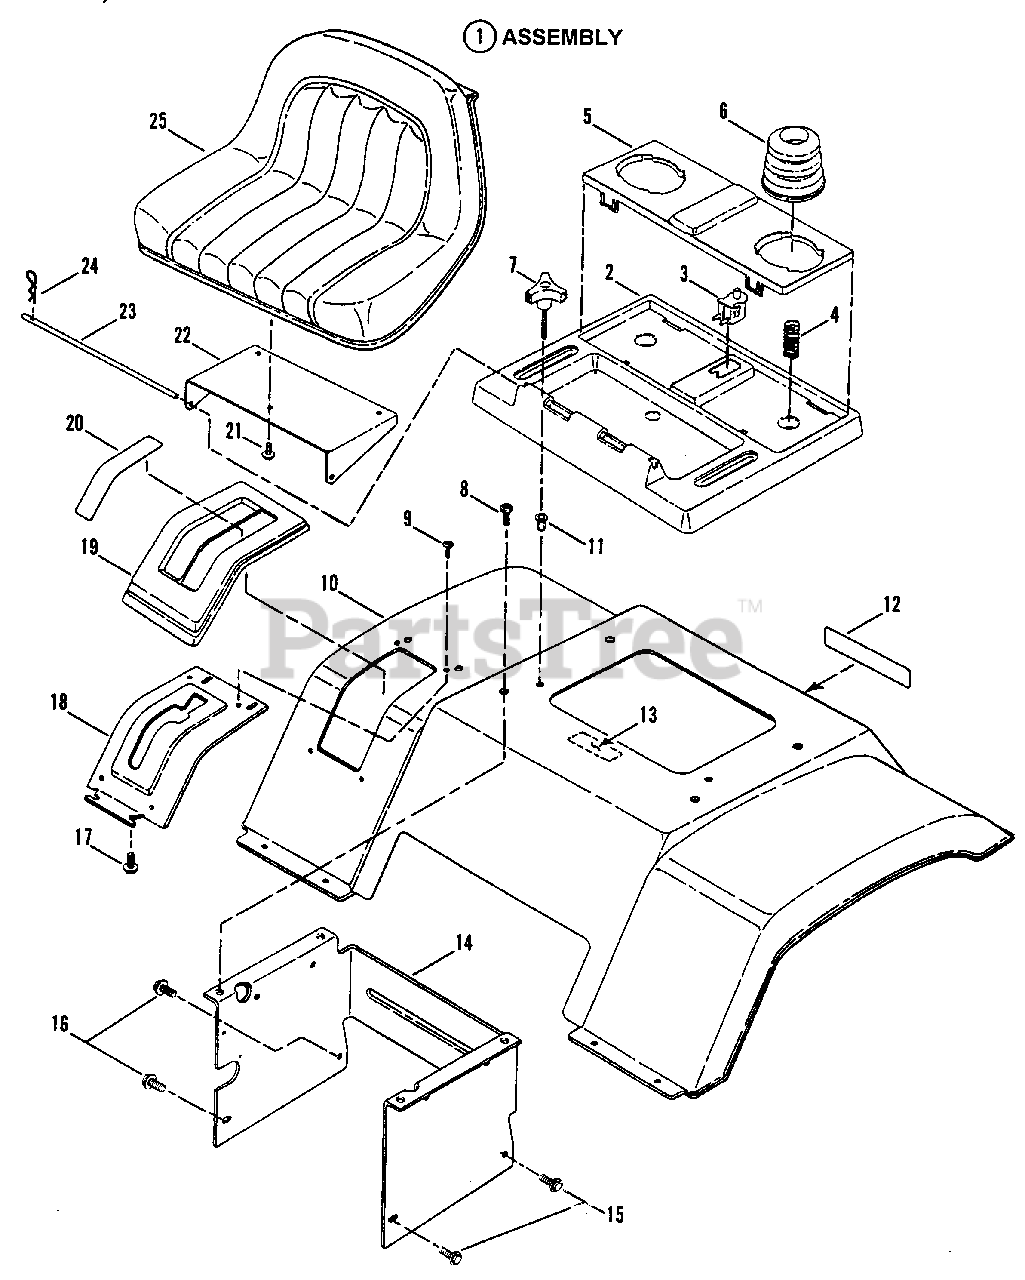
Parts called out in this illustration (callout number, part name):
1	ASSEMBLY, Seat Support
2	SUPPORT, Seat
3	SWITCH, Seat
4	SPRING
5	HOLDER, Cushion
6	CUSHION, Seat
7	KNOB, Seat Adjustment
8	SCREW, 5/16-18 x 5/8" Truss Head, Torx
9	SCREW, 1/4-20 x 5/8" Hex Washer Head, Self-Tapping
10	PAN, Seat (Fender)
11	RIV-NUT, 5/16-18 Round
12	DECAL - SNAPPER, 7.28" Molded Logo, White Letters & Stripe
12	DECAL - SNAPPER, 7.28" Molded Logo, Silver Letters & Blue Stripe
13	DECAL - CAUTION, Battery Location
14	SUPPORT, Fender
15	SCREW, 5/16-18 x 5/8" Hex Washer Head, Swage Form
16	SCREW, 5/16-18 x 1 114" Hex Washer Head, Swage Form
17	SCREW, #10-16 x 1/2" Hex Washer Head, Self-Tapping
18	DETENT, Shift (Gear Drive)
18	DETENT, Shift (Hydro Drive)
19	COVER, Shift
20	DECAL, Shift Cover, 5-Speed (Gear Drive)
20	DECAL, Shift Cover, 5-Speed (Hydro Drive)
21	BOLT, 5/16-18 x 1/2" Hex Flange Lock
22	BRACKET, Seat Support
23	ROD, Seat Hinge
24	PIN, 3/32 x 1 1/2" Hair
25	SEAT, Operator's
